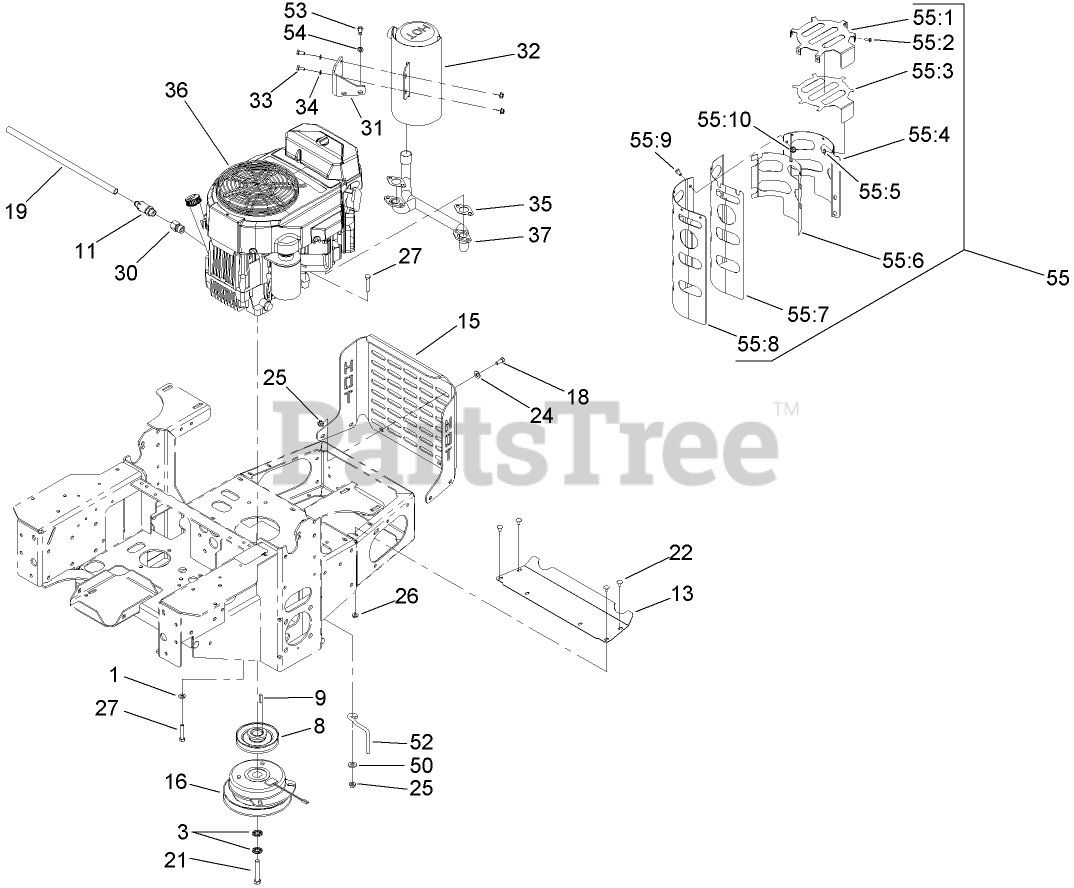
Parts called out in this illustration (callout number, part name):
1	WASHER-SPRING
3	WASHER-SPRING
8	PULLEY
11	VALVE-DRAIN, OIL
13	Deflector-Short
15	BUMPER-REAR
16	CLUTCH
18	SCREW-HH
19	TUBE-DRAIN, OIL
21	SCREW-HH
22	SCREW-CARR
24	WASHER-FLAT
25	NUT-HF
26	NUT-HF
27	SCREW-HH
30	Adapter
31	BRACKET-MUFFLER
32	MUFFLER
33	SCREW-HH
34	WASHER-SPRING
35	GASKET-EXHAUST
37	MANIFOLD-EXHAUST
50	WASHER-FLAT
52	ROD-BELT
53	SCREW-HH
54	WASHER-LOCK
55	MUFFLER GUARD ASM
55:1	GUARD-MUFFLER, CAP
55:2	SCREW-HWH
55:3	FOIL-TAPE, CAP
55:4	GUARD-MUFFLER, LH
55:5	NUT-HEX, SIDE LOCK
55:6	FOIL-TAPE, LH
55:7	FOIL-TAPE, RH
55:8	GUARD-MUFFLER, RH
55:9	SCREW-HH
55:10	NUT-HF
